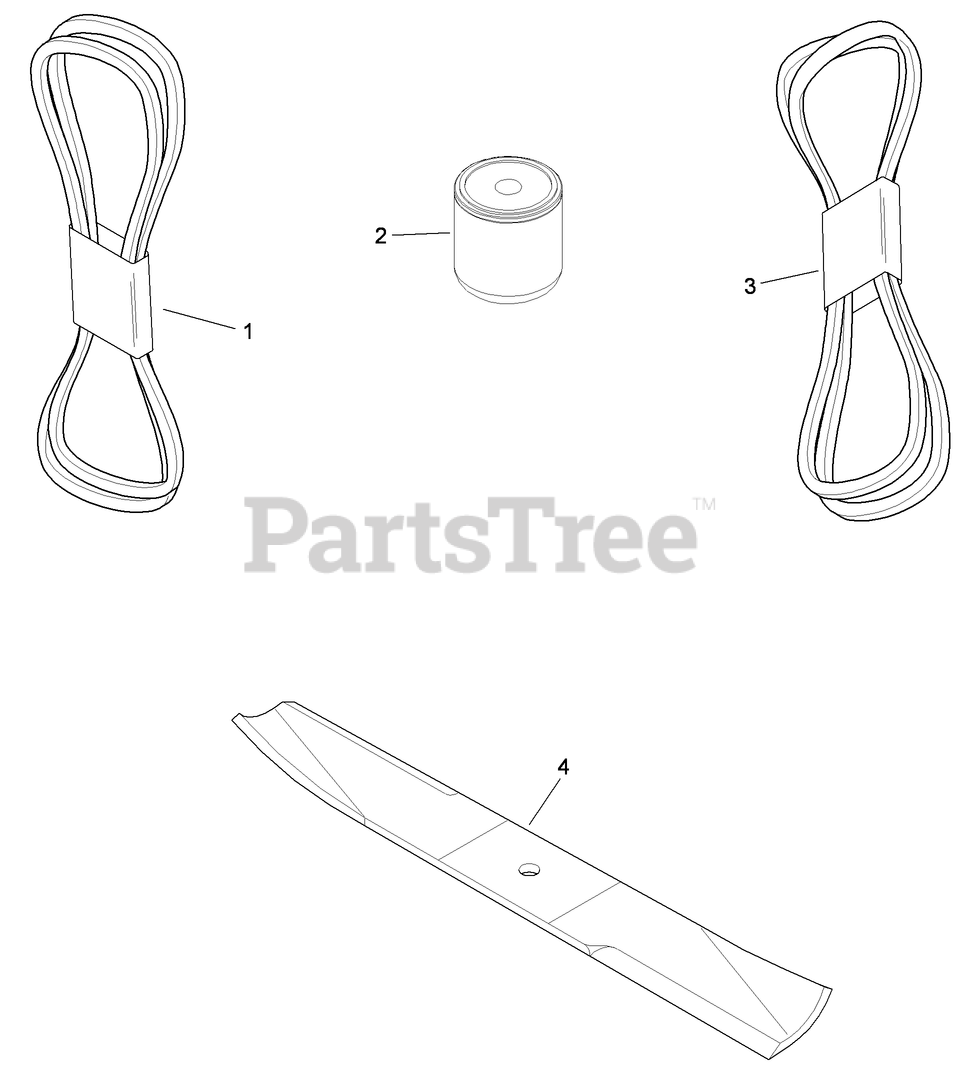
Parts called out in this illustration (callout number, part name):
1	BELT-PUMP
2	FILTER-OIL, HYD
3	BELT-DECK (52)
4	BLADE-18 INCH
